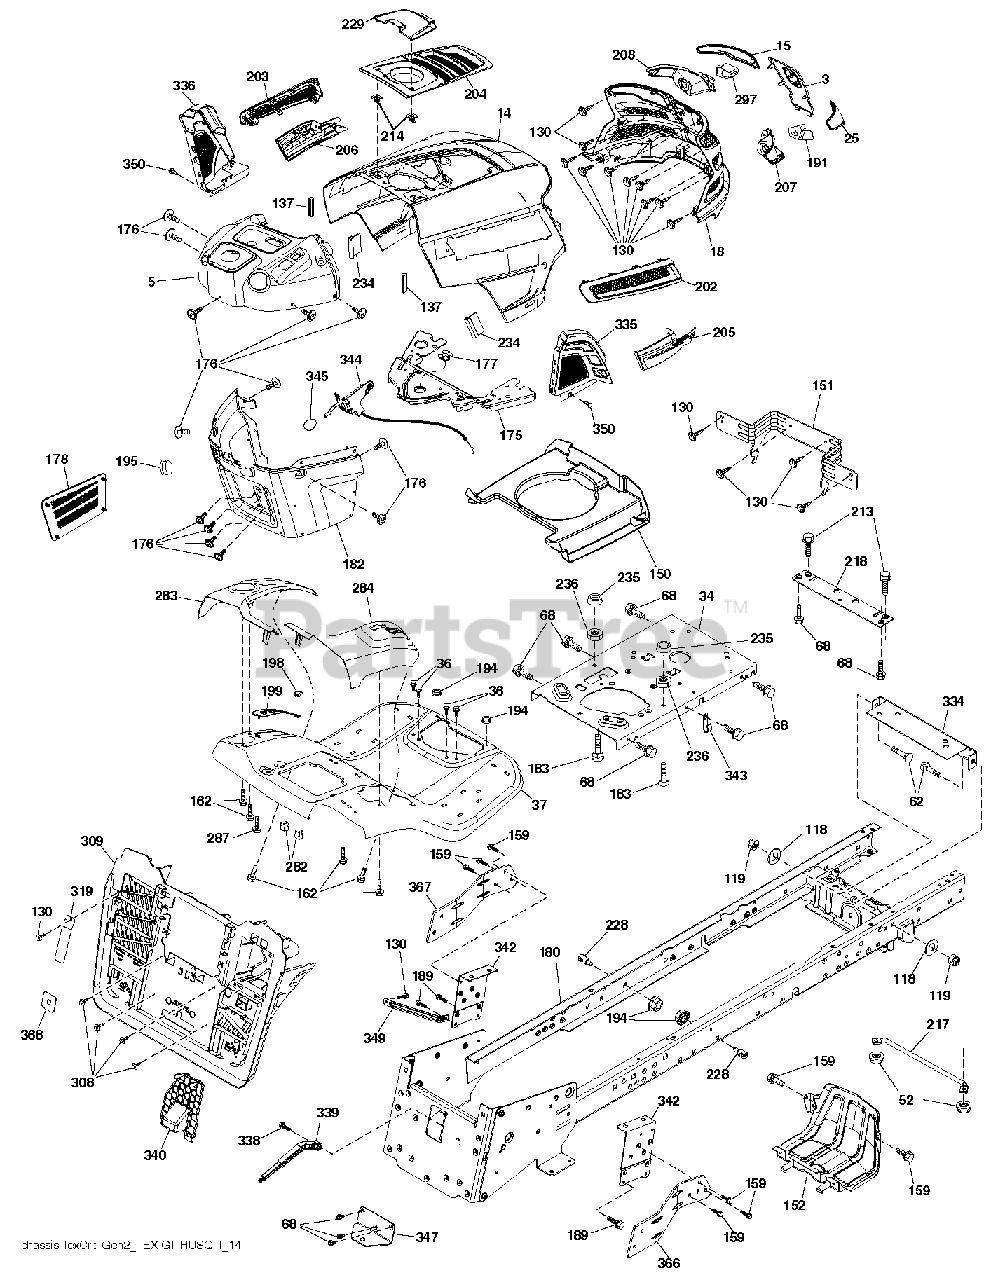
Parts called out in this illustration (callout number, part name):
3	APPLIQUE.SUBASM.GT.HUSQ.II
14	HOOD.ASM.HUSQVARNA.GT.TEX.ORAN
15	LENS.HEADLIGHT.LH.GTII.2011
18	GRILLE.SUBASM.GT.HUSQ.II
25	LENS.HEADLIGHT.RH.GTII.2011
34	PLATE.ENGINE.10GA.CRD.GENII
36	SCREW 5/16"
37	FENDER.TEX.SRD.CRD.BASE
52	LOCKNUT
62	BOLT D
68	SCREW LT
118	WASHER
130	SCREW.#10 X 0.750.BOS
137	BUMPER DASH
150	AIR DUCT.GTV2(1.66"RING HEIGHT
151	BRACKET.PIVOT.HOOD.GT.HUSQ.II
152	SHIELD.BROWNING.PNT.GT.V2
159	SCREW, 3/8-16X3/4
162	SCREW.HI-LO.CONSOLE
175	PLATE.CROSSMEMBER.HUSQ
176	SCREW.#10-24X5/8.RN.QU
177	BUSHING, STEERING
178	CARGO.ASM.NET.TXGT.W/C
180	WELDMENT.CHASSIS.TEX.CRD.GEN.2
182	DASH DASH LOWER
183	BOLT.5/16-18X1-1/4 FULL THD
189	SCREW
191	INSERT.REFLECTIVE.RH.HUSQ.GTII
194	NUT LOCK HEX FLANGE 5/16-18
195	PLUG.HOLE.DASH.LOWER.12V.BLK
198	INDICATOR.DECK.LIFT.RED
199	PLATE DECK LIFT
202	VENT.SIDE.RH.GT.HUSQ.II.
203	VENT.SIDE.LH.GT.HUSQ.II.498
204	VENT.TOP.EXTERNAL.FILL.GT2.GRE
205	SIDE.TRIM.RH.GT.HUSQ.II
206	SIDE.TRIM.LH.GT.HUSQ.II.GRAY
207	BEZEL LIGHT.RH.GT.II.MYLAR
208	BEZEL LIGHT.LH.GT.II.MYLAR
213	BOLT
214	CLIP.RETAINER.TINNER.
217	ROD.PIVOT.HOOD
218	X-PIECE.HOOD.STOP.NON/
228	STUD.FASTNER.W/ANTI-ROTATE
229	LID.EXT.FILL.GT.HUSQ2.BLACK
234	BUMPER.HOOD.TEX.HUSQVARNA
235	SPACER FENDER
236	NUT.CENTERLOCK.5/16-
282	CLIP.RETAINER.CONSOLE.LT.HUSQ
283	CONSOLE.DECKLIFT.CRDII.498
287	SCREW 1/4X20
297	INSERT.REFLECTIVE.LH.HUSQ.GTII
308	BOLT, 5/16-18 X 1 3/4
309	BACKPLATE.ASM.CRDII.ANTIROTAT
319	LEVER.BAG.CRDII.ANTIROTATION
334	BRACKET.ENGINE
335	COVER.LOWER.DASH.RH.BLACK
336	COVER-LH.LOWER.DASH.GT2.BLACK
338	BOLT BOLT SHOULDER
339	LEVER LEVER BAGGER
340	BATTERY.DOOR.TEX.CRD.GEN.2,1
342	SUPPORT SUPPORT FENDER
343	CLIP CLIP
344	CONTROL.EZ.MULCH.TEX/CRD
345	RP KNOB.OVAL.TAPERED.3/8-16BLK
347	HITCH HITCH TOW TEX CRD GEN 2
349	BRACKET.SUPPORT.LRVB/CRD
350	CLIP.X-MAS.TREE
366	BRACKET.RH.FRONT.BAGGER.BLACK
367	BRACKET.LH.FRONT.BAGGER.BLACK
368	FULL.LEVER.BAGGER.TEX.CRD
